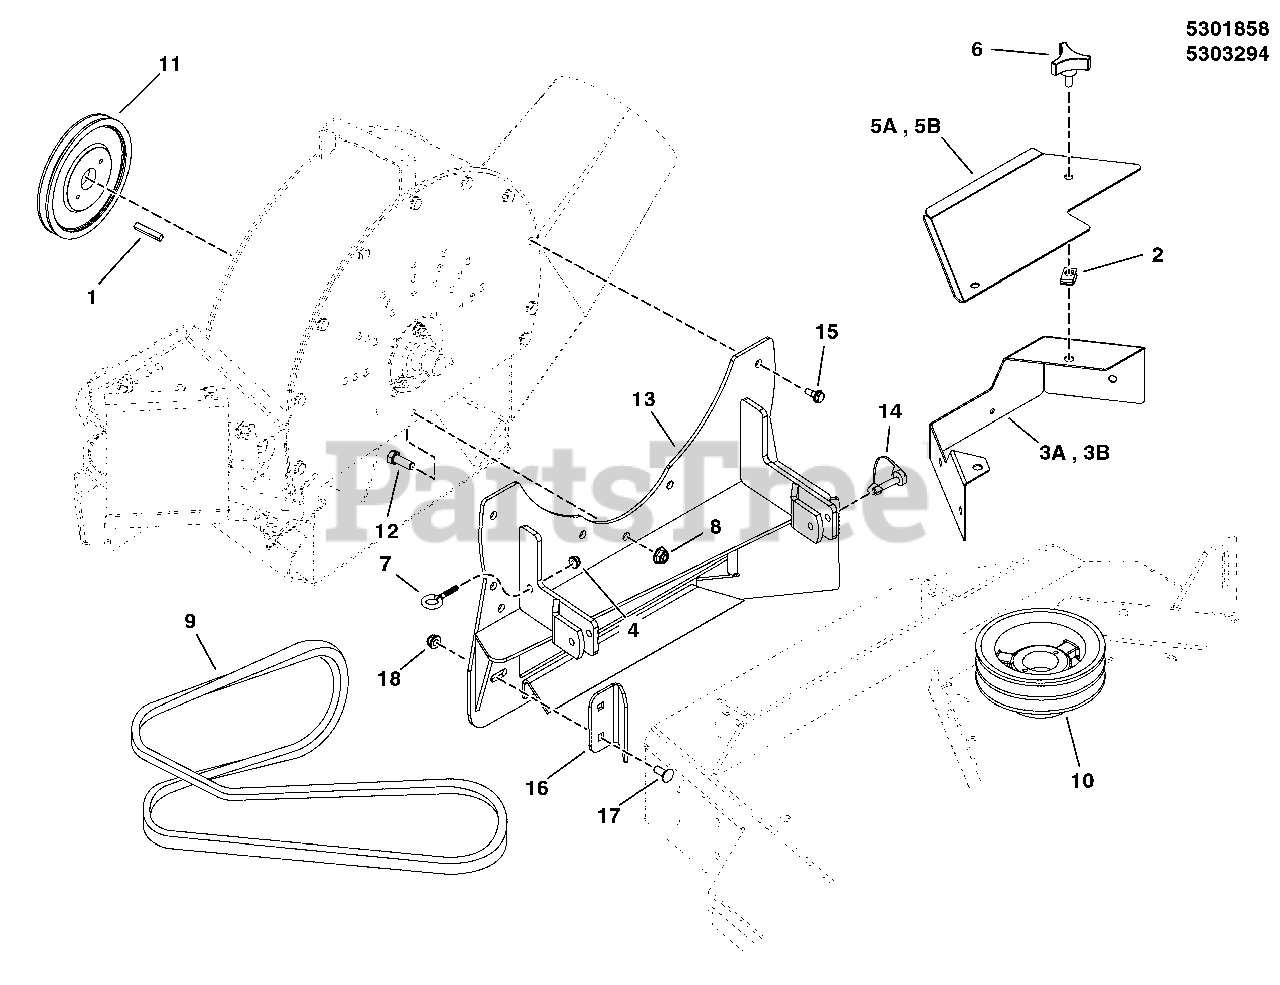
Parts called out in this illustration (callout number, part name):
1	KEY 1/4 SQ X 1 1/2 LONG
2	BODY CLIP, 5/16-18-7GA MATERIAL
4	NUT, 1/4-20 HEX NYLOCK FLANGE (5025391)
6	KNOB, PLASTIC, 5/16-18 X 3/4
7	EYEBOLT, 1/4-20 X 2
8	NUT, 3/8-16 HEX NYLOCK FLANGE
9	BELT, A-SEC, 92.00EL, ARAMID, WRPD
10	PULLEY-BLOWER 52 DECK
11	PULLEY, BC-46, 4.55 OD X 1.00 ID
12	BOLT, 3/8-16 X 1 GD5 YZ
13	WELD, BLOWER MOUNT, 52 - BLK
14	SNAPPERPIN, 5/16 X 2
15	BOLT, 5/16-18 X 5/8" Self Lock
16	BRACKET,DEFLECTOR PLATE,52iCD 2011 - BLK
17	BOLT, 5/16-18 X 3/4, CARRIAGE
18	NUT, 5/16-18 HEX NYLOCK FLANGE
